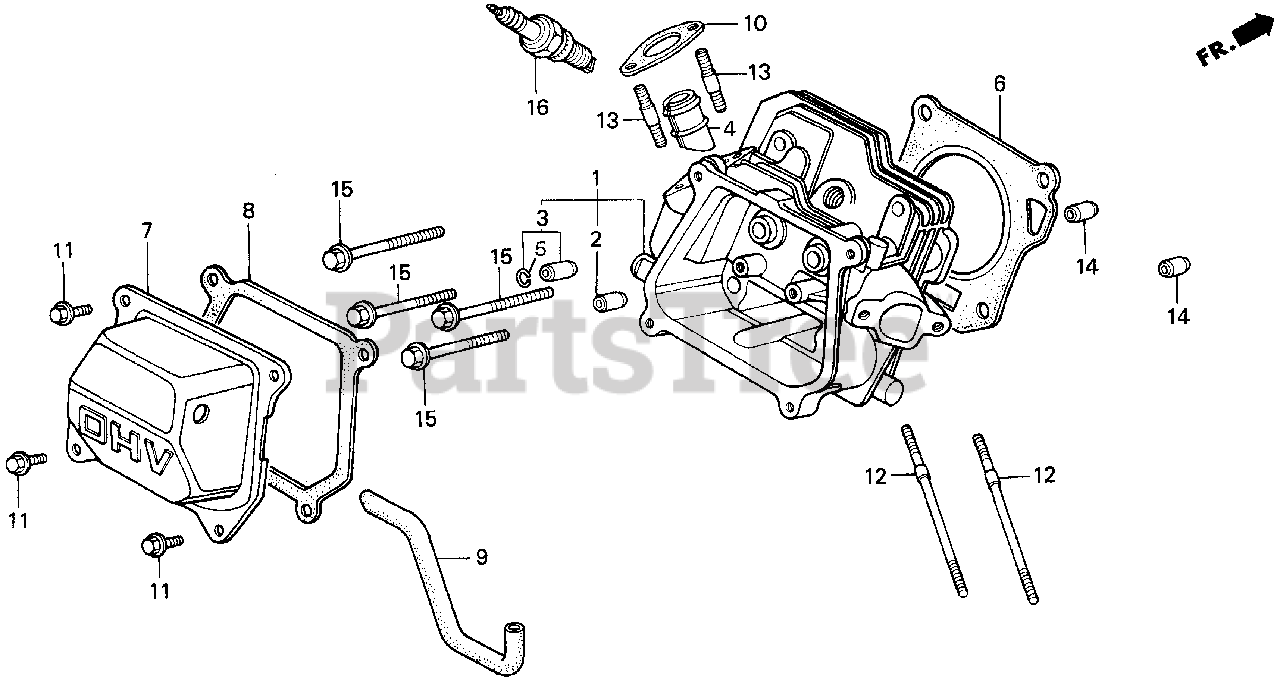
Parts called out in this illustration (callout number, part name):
1	CYLINDER HEAD
2	GUIDE, VALVE (OS)
3	GUIDE, EX. VALVE (OS)
4	LINER, PORT (NOT AVAILABLE)
5	CLIP, VALVE GUIDE
6	GASKET, CYLINDER HEAD
7	COVER, HEAD
8	GASKET, CYLINDER HEAD COVER
9	TUBE, BREATHER
10	GASKET, MUFFLER
11	BOLT, FLANGE (6X13)
12	BOLT, STUD (6X94)
13	BOLT, STUD (8X32)
14	PIN A, DOWEL (10X16)
15	BOLT, FLANGE (8X60)
16	SPARK PLUG (BPR6ES) (NGK)
16	SPARK PLUG (W20EPR-U) (DENSO)
